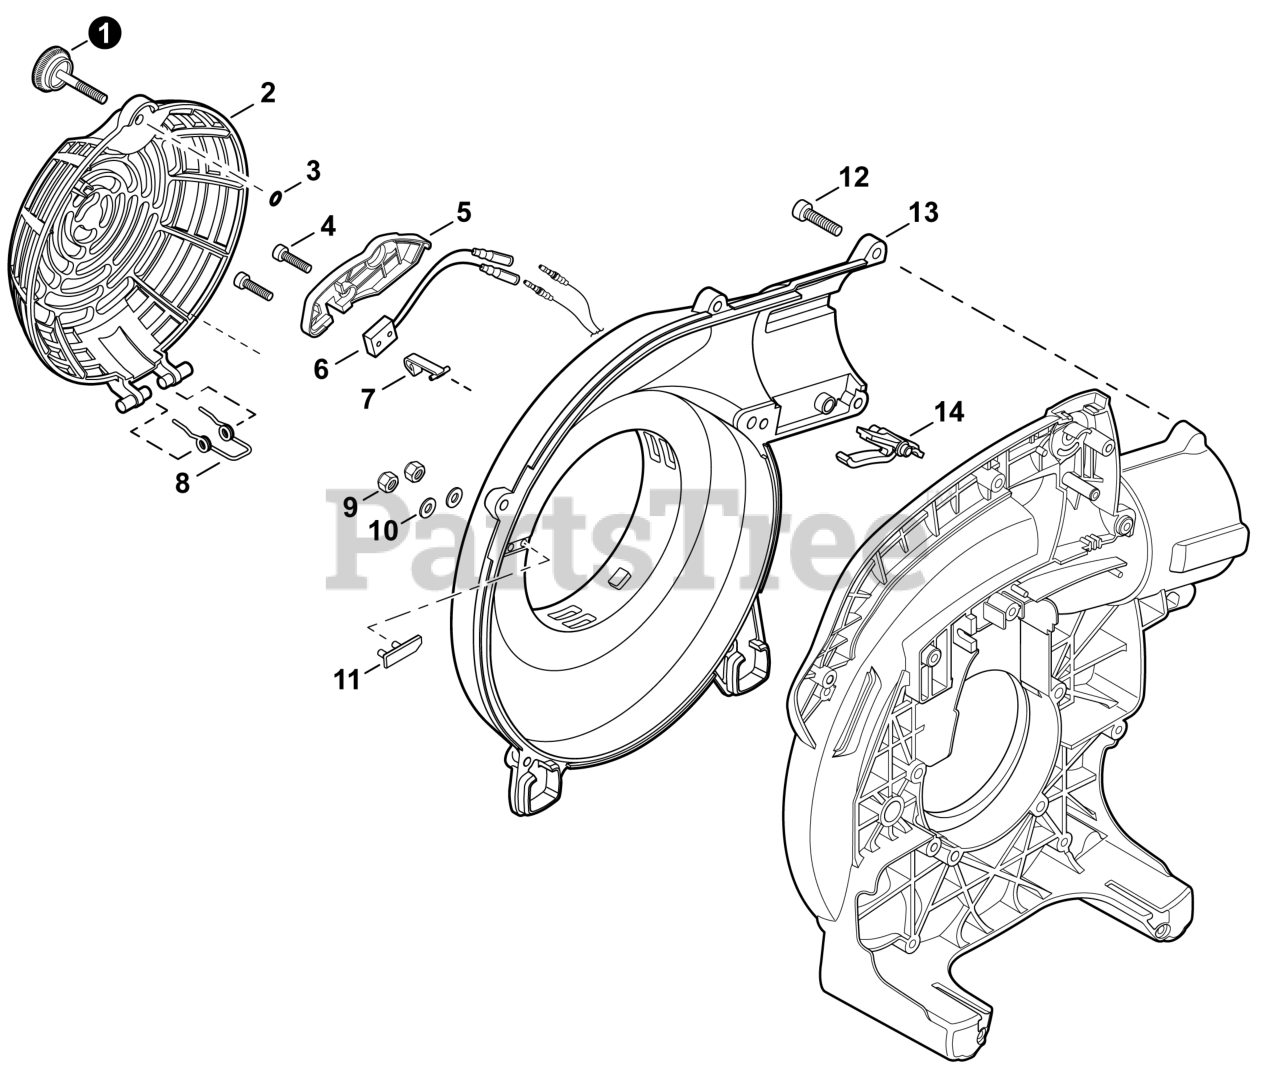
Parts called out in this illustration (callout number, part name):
1	THUMBSCREW
2	GUARD, FAN
3	O-RING 3
4	BOLT, TORX 4×16
5	COVER, SWITCH
6	SWITCH, SAFETY
7	LEVER, ACTUATOR
8	SPRING, TORSION
9	NUT, LOCK M5
10	WASHER 5.5×12×0.8
12	BOLT, TORX 5×20
13	COVER, FAN
14	LOCK, TUBE
